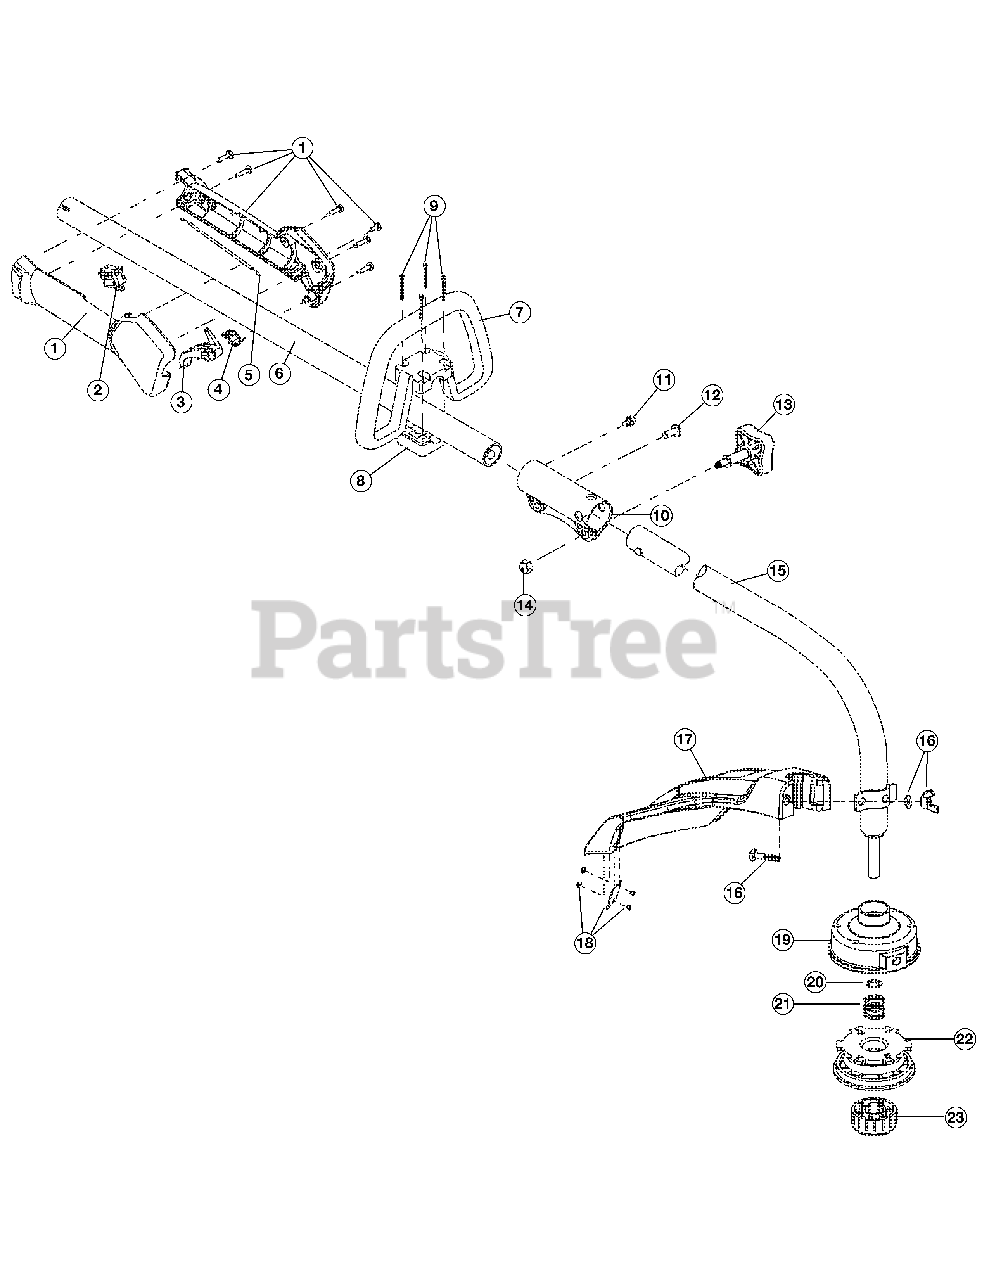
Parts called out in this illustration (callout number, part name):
1	Throttle Housing Assembly (includes 2-4)
3	Throttle Trigger
4	Throttle Trigger Spring
5	Throttle Cable
6	Upper Drive Shaft Housing Assembly
7	Deluxe D-Handle (includes 8 & 9)
8	Deluxe D-Handle Base
10	Split Boom Coupler (includes 11-14)
13	Adjustment Knob
14	Knob Retaining Nut
15	Lower Drive Shaft Housing Assembly
16	Guard Mounting Hardware
17	Guard Assembly (includes 18)
18	Blade Assembly
19	Outer Spool Assembly (includes 20)
22	Inner Reel
23	Bump Head Knob Assembly
